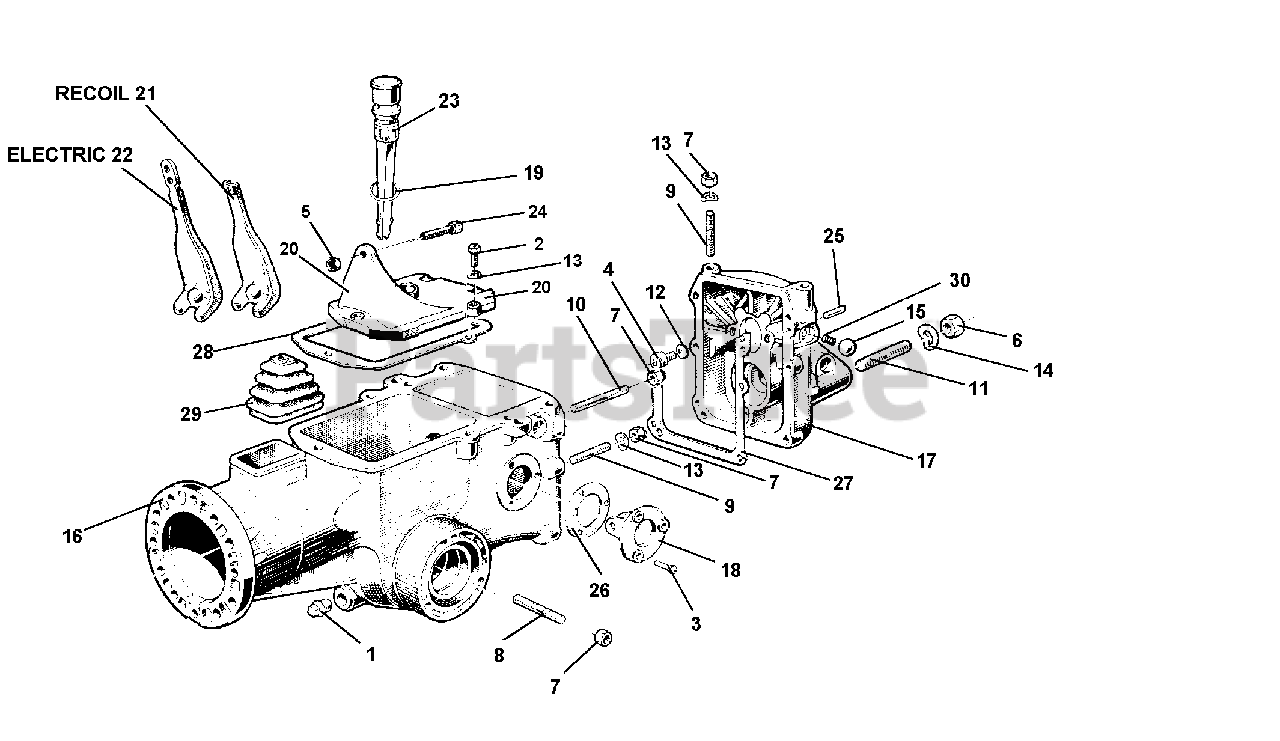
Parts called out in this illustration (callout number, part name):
1	PLUG 1/4 GAS
2	SCREW TE M8 X 25
3	SCREW M6 X 16
4	SCREW TCCEI M8 X 12
6	NUT M12 X 1.25 UNI 5587 6S
7	NUT, SELF LOCKING M8
8	STUD M8 X 46 X 20 X 12
9	STUD M8 X 46 X 16 X 16
10	STUD M8 X 58 X 16 X 16
11	ST.56XM12X1.25X26XM12X22 8G
12	SUPER WASHER 8 DIN 6796
13	WASHER, LOCK 8.4
14	WASHER, LOCK 13
15	BALL 15/32 RIV RB-11.906
16	HOUSING BODY
17	HOUSING COVER
18	REVERSE SPEED FLANGE
19	RUBBER RING
21	CLUTCH LEVER
22	CLUTCH LEVER
23	CAP, WITH MEASURING ROD
24	SCREW, ADJUSTING M8
25	PARALLEL PIN D 6 X 20
27	GASKET, COVER
28	GASKET, COVER
30	P.T.O. SPRING
